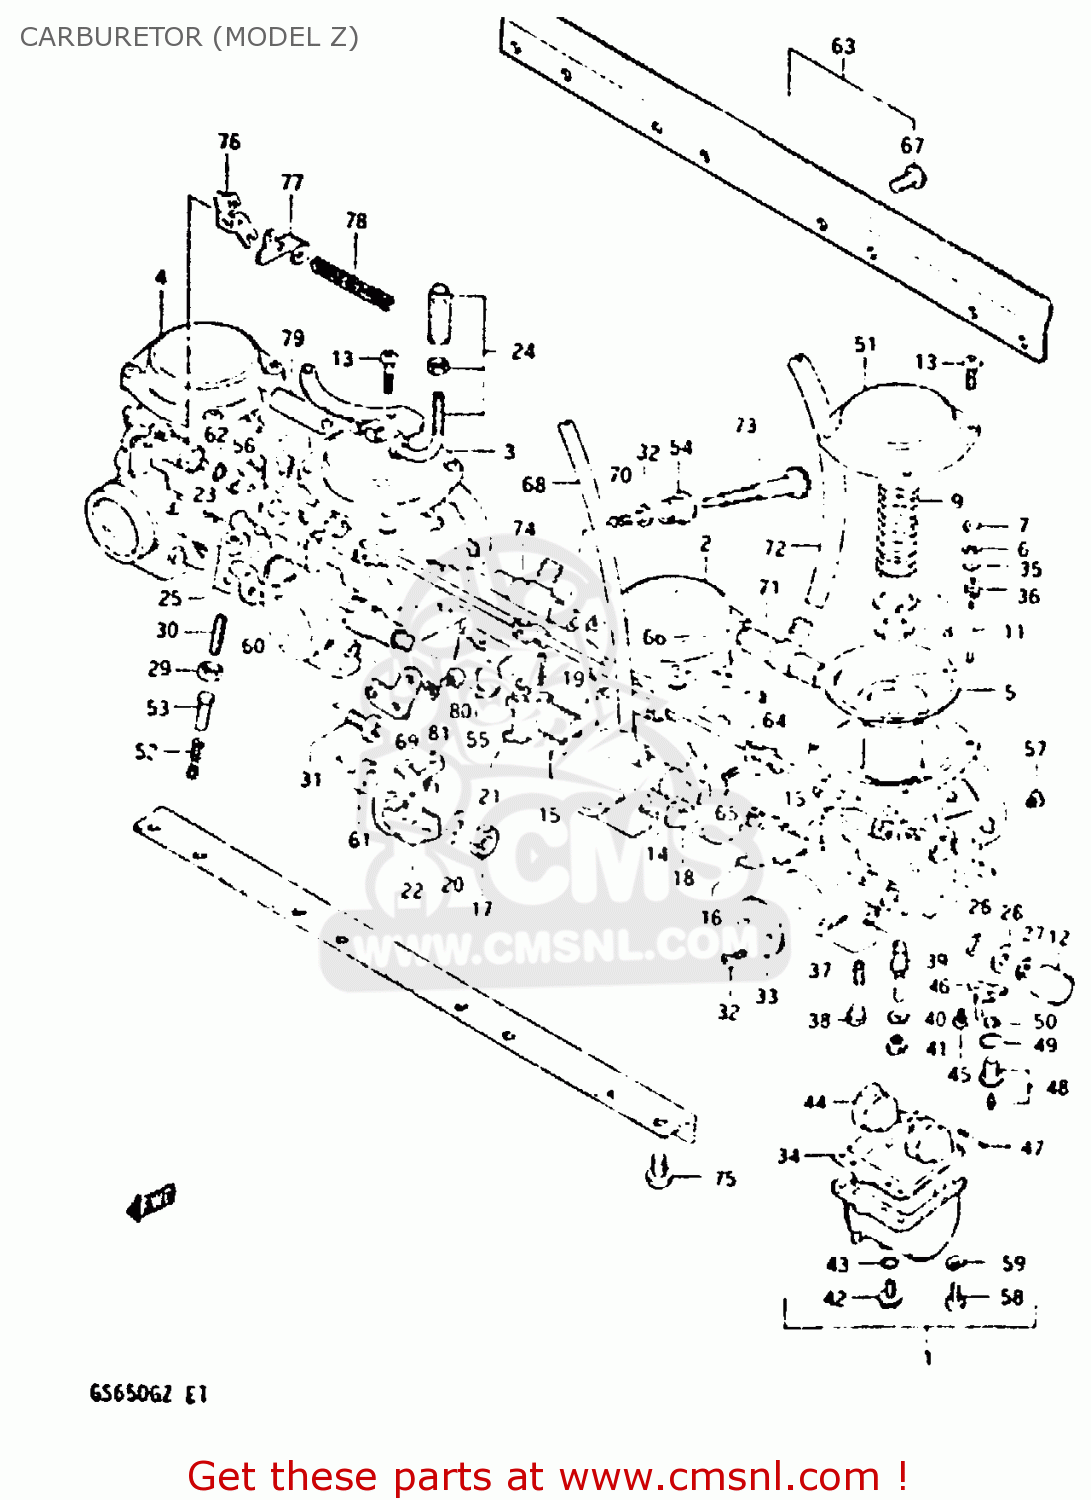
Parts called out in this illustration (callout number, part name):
1	CARBURETOR, LH
2	CARBURETOR, ML
3	CARBURETOR, MR
4	CARBURETOR, RH
5	DIAPHRAGM
6	CLIP,NEEDLE
7	RING
8	HOLDER,GUIDE
9	SPRING
10	E RING
11	NEEDLE, JET (5C47-3)
12	CAP
13	SCREW
14	GASKET,THROTTLE SHAFT (NAS)
15	SPRING,THROTTLE SHAFT
16	SHAFT,THROTTLE
17	NUT 8MM
18	SHAFT,THROTTLE
19	PIN,THROTTLE SHAFT
20	WASHER
21	LEVER,THROTTLE SHAFT
22	LEVER ASSEMBLY,THROTTLE
23	SPRING
24	BRACKET,THROTTLE CABLE
25	SHAFT,THROTTLE
26	SEAL
27	E RING
28	GASKET,THROTTLE SHAFT (NAS)
29	NUT
30	SCREW
31	SCREW
32	SCREW
33	THROTTLE VALVE (135)
34	GASKET,FLOAT CHAMBER (NAS)
35	WASHER
36	SPRING
37	JET, PILOT (42.5)
38	PLUG,NEEDLE JET
39	JET, NEEDLE (Y-7)
40	WASHER,NEEDLE NOZZLE
41	JET, MAIN
42	PLUG,DRAIN
43	GASKET (NAS)
44	FLOAT
45	SCREW 4X6
46	PLATE,NEEDLE VALVE FITING
47	PIN,FLOAT
48	VALVE ASSEMBLY,NEEDLE
49	O-RING,NEEDLE VALVE
50	FILTER
51	COVER,DIAPHRAGM
52	SPRING,THROTTLE SCREW
53	PIN,THROTTLE LEVER
54	BUSH
55	BRACKET,THROTTLE ADJUST
56	CAP,STARTER VALVE
57	JET,AIR(140)
58	SCREW
59	LOCK WASHER
60	SHAFT,THROTTLE
61	WASHER
62	O RING
63	CARBURETOR ASSEMBLY
64	LEVER
65	SCREW
66	SHAFT,STARTER
67	SCREW
68	HOSE
69	BRACKET,THROTTLE ADJUST
70	SPRING
71	NIPPLE
72	HOSE
73	SCREW
74	NIPPLE,CARBURETOR
75	SCREW 6X12
76	LEVER,CHOKE CABLE
77	PLATE,CHOKE CABLE
78	SPRING,CHOKE CABLE
79	NIPPLE
80	SCREW
81	LOCK WASHER
82	WASHER
